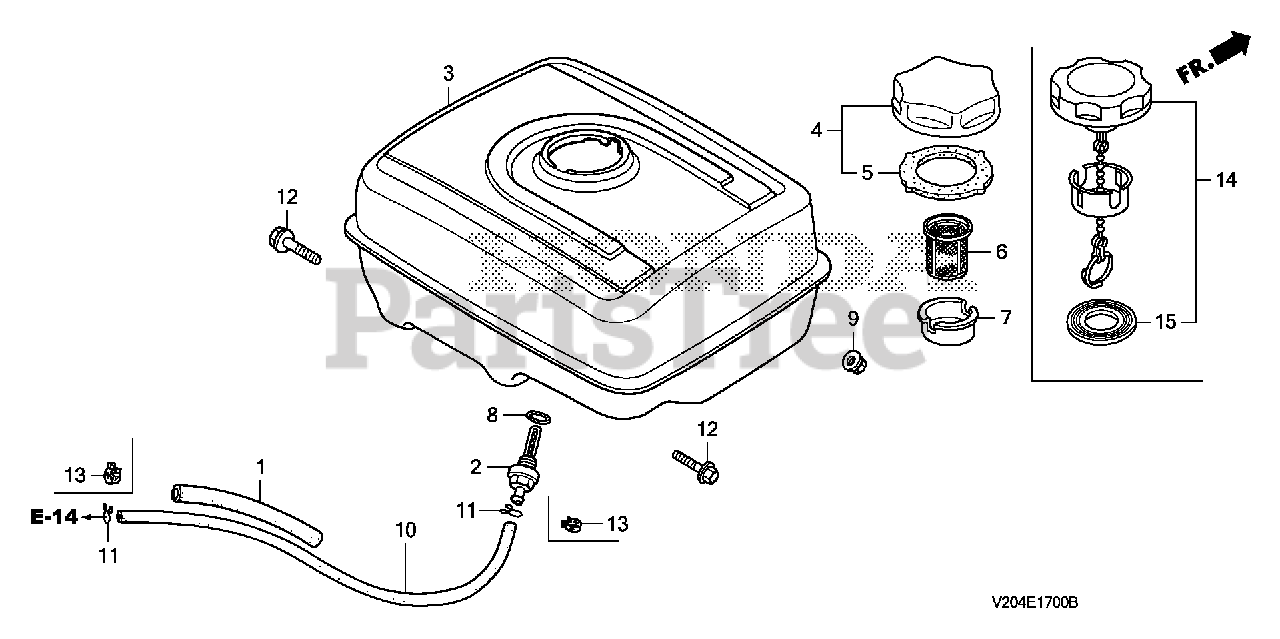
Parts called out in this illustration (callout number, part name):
1	RUBBER, SUPPORTER (107MM)
2	JOINT, FUEL TANK
3	TANK, FUEL *R280* (POWER RED)
4	CAP, FUEL FILLER
5	GASKET, FUEL FILLER CAP Use from Engine SN 1543258.
5	GASKET, FUEL FILLER CAP (39X58X3)
6	FILTER, FUEL
7	HOLDER, FUEL FILTER
8	O-RING (14MM) (ARAI) Use up to Engine SN 2949254.
9	NUT, FLANGE (8MM)
10	TUBE, FUEL (4.5X222) (FKM)
10	TUBE, FUEL (4.5X222)
10	BULK HOSE, FUEL (4.5X3000) (Honda Code 5137104). (4.5X140)
11	CLIP, TUBE (B8)
12	BOLT, FLANGE (8X25)
13	CLIP, TUBE (D8)
